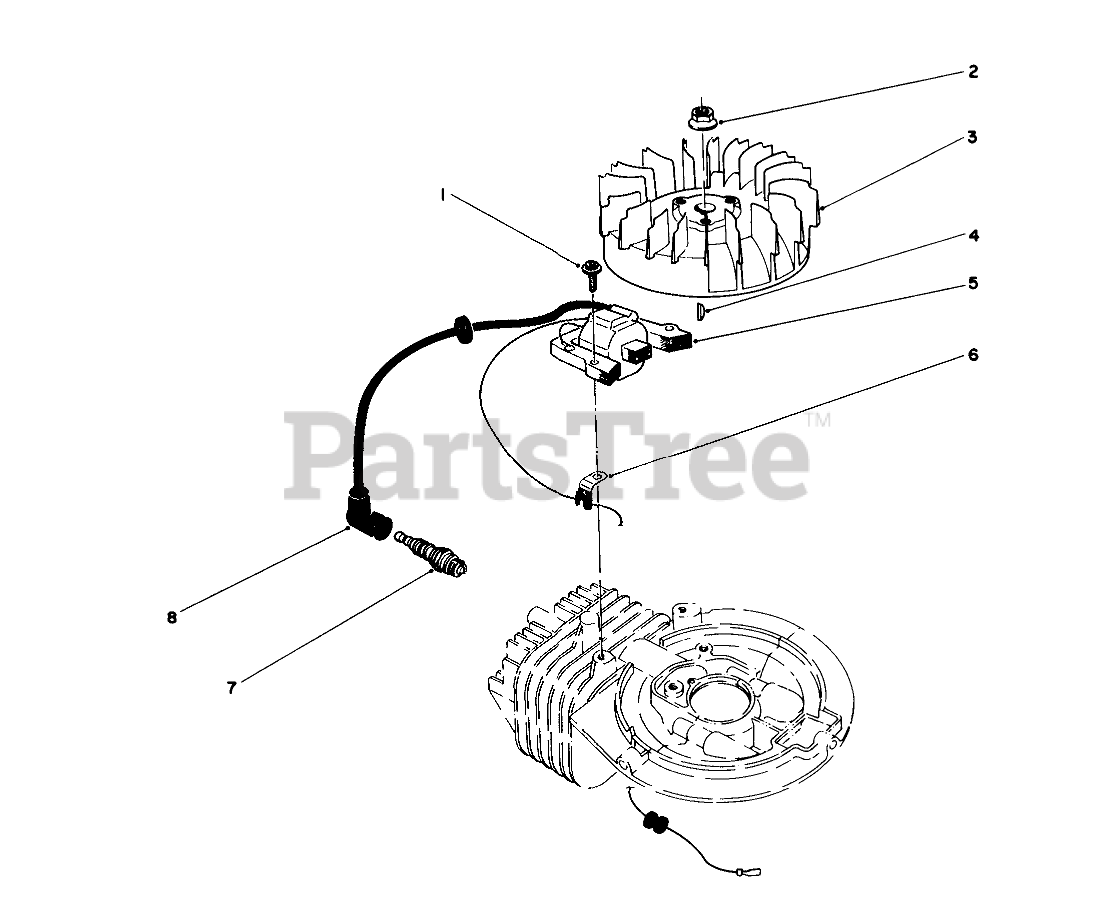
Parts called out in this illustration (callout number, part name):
1	SCREW
3	FLYWHEEL
5	COIL-MAGNETO
6	CLAMP
7	Sparkplug
8	CAP-SPARKPLUG
